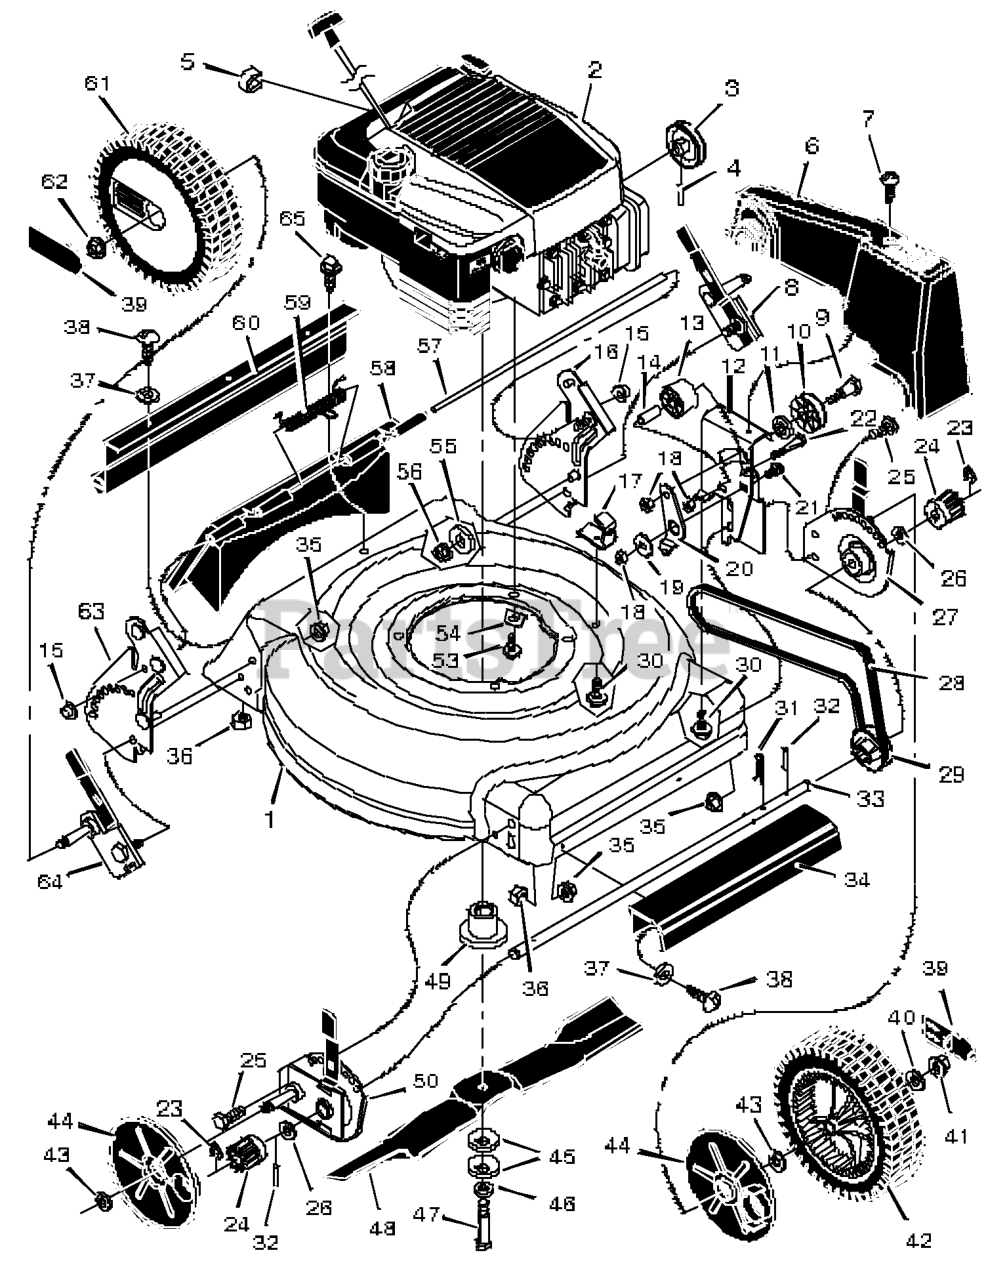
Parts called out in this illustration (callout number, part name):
1	Housing
2	Engine
3	Pulley, Engine
4	Pin, Spring
5	Stop, Rope (Recoil - Start)
6	Cover, Belt
8	Adjuster, Left Height
9	Bolt, Shoulder
12	Bracket, Idler Support
13	Pulley, Idler
14	Bearing
15	Push On Cap
16	Bracket, Left Handle
17	Bracket, Cable
18	Nut, Hex
20	Arm, Idler
21	Bolt, Carriage
22	Bolt, Shoulder
24	Gear, Pinion
25	Bolt
27	Adjuster, Left Front Height
29	Pulley, Axle
31	Pin, Hair
32	Pin, Spring
34	Cover, Axle
35	Nut, Flange
36	Nut, Hex
39	Hub Cap
40	Washer
41	Nut, Flange
42	Wheel, Drive
44	Cover, Dust
45	Washer, Belleville
49	Adapter, Blade
50	Adjuster, Right Front Height
53	Bolt, Engine
54	Support, Engine
55	Washer
56	Nut, Flange
57	Rod, Pivot
58	Door, Rear
60	Guard, Rear
61	WHEEL & TIRE ASSEMBLY, White, 8"
62	Nut, Flange
63	Bracket, Right Handle
64	Adjuster, Right Height
